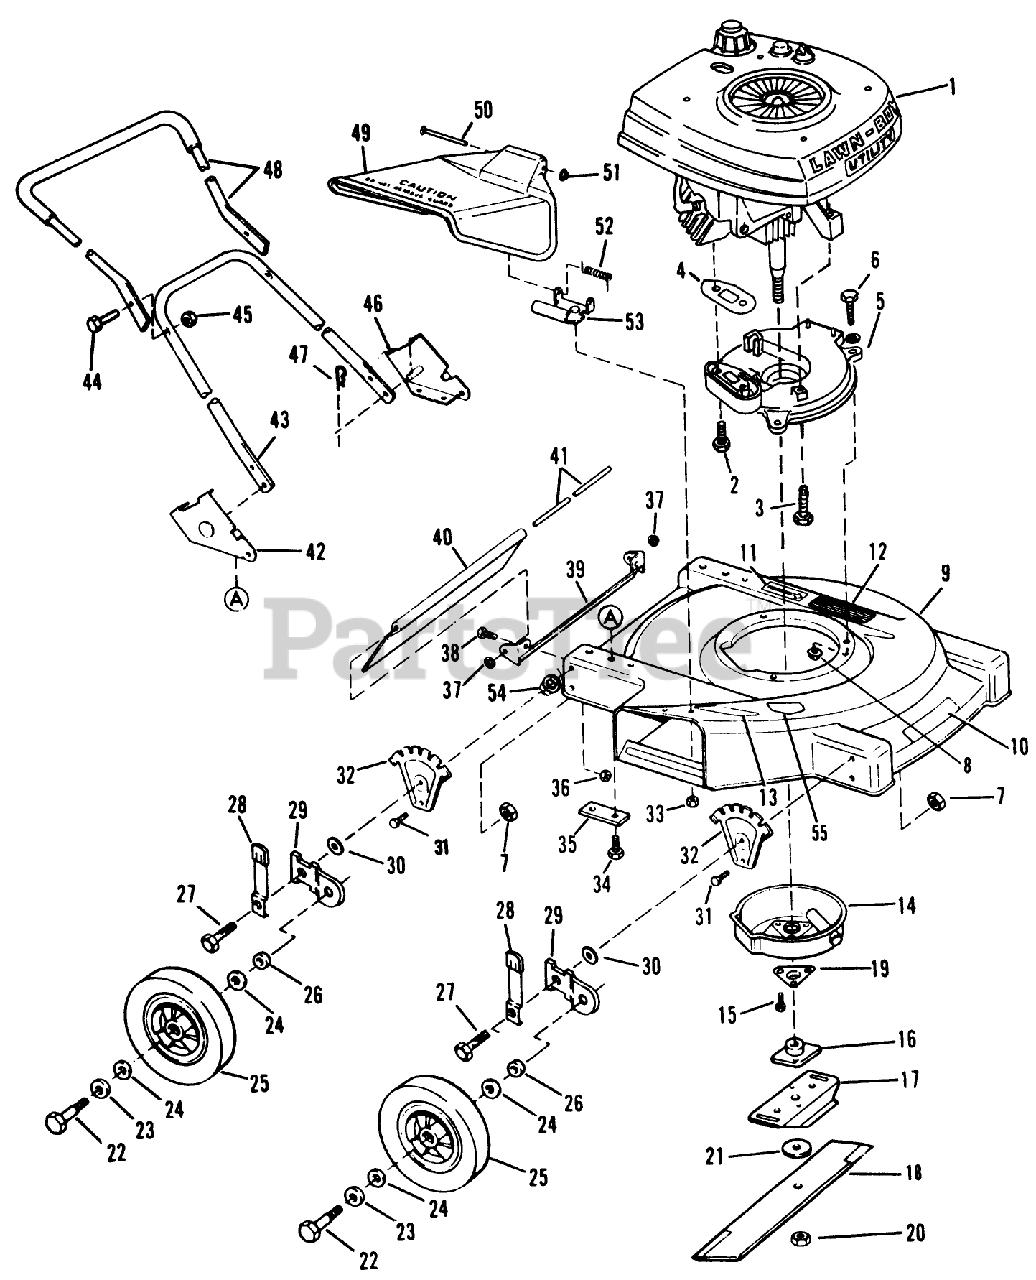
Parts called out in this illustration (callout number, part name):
2	SCREW V
5	PLATE,MUFFLER F
6	SCREW
7	LOCKNUT
8	NUT-LOCK F
12	PAD FOOT
15	SCREW
16	PLATE AND COLLAR ASM
18	BLADE EURO WHIRL
19	SUPPORT F
20	NUT-BLADE
21	WASHER
22	BOLT WHEEL
23	SPACER
24	WASHER
26	WASHER WROUGHT
27	BOLT
28	KNOB&SPRING FORMCO
30	WASHER
33	LOCKNUT E
34	SCREW
36	LOCKNUT E
39	BRACKET (12)
40	TRAILING SHIELD
44	SCREW - USE 137-3042
45	LOCKNUT E
47	HAIR PIN
49	CHUTE DEFLECTOR AY
50	PIN
53	HINGE & SCREW ATA
54	WASHER
